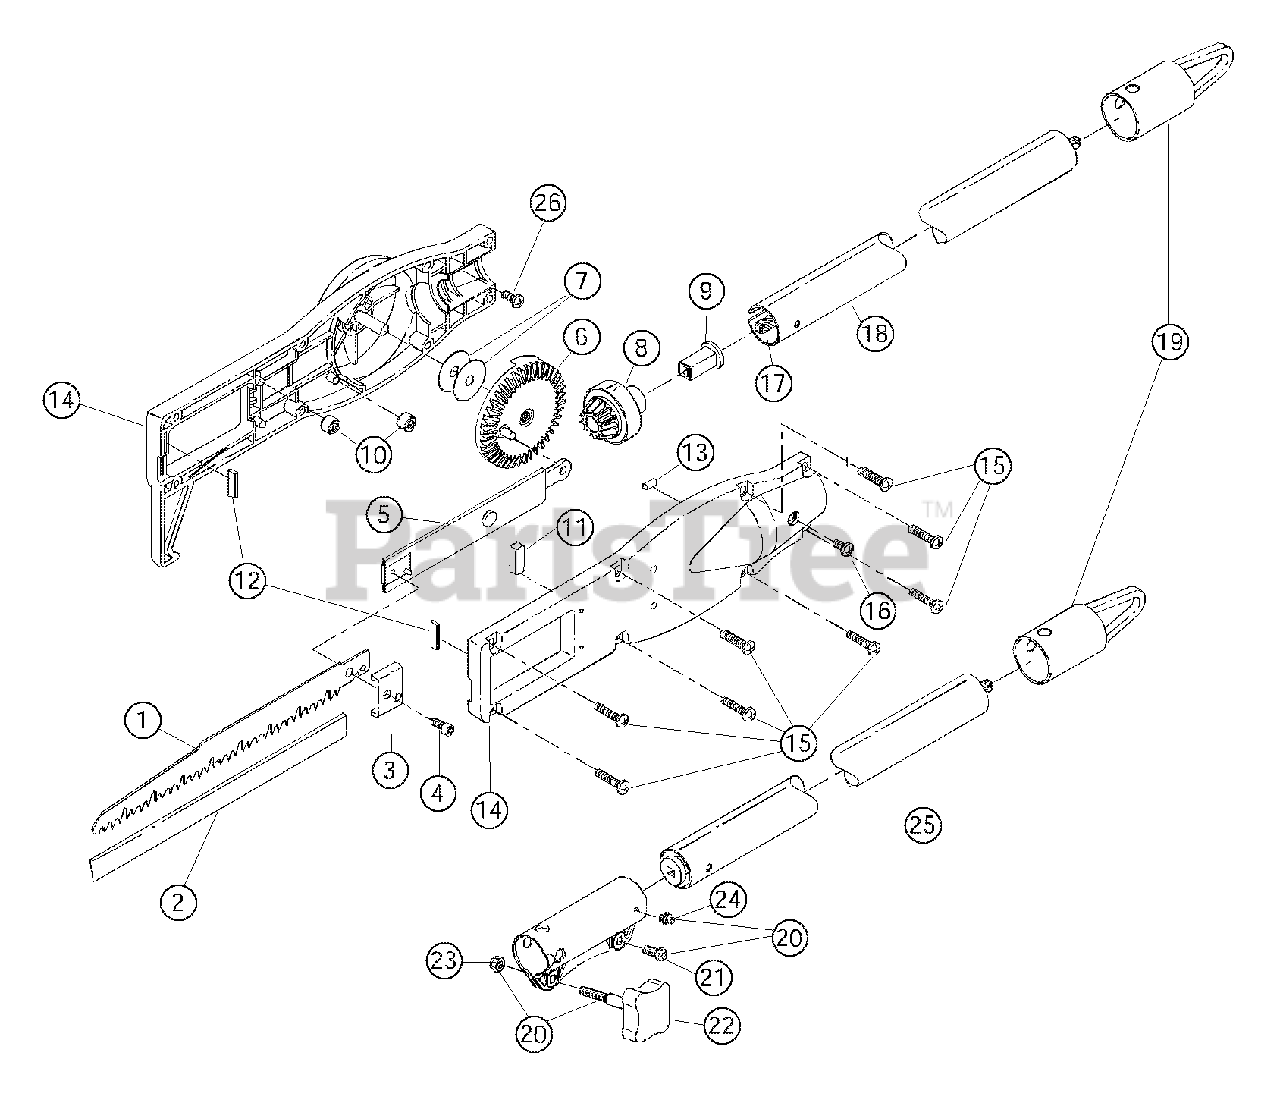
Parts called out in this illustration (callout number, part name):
1	Blade (2 pack)
2	Blade Cover
3	Blade Clamp
4	Blade Clamp Screw & Washer Assembly
5	Arbor Assembly
6	Bevel Gear
8	Pinion Bevel Gear
9	Insulator
10	Slide Bushing
11	Felt Seal
12	Slider (2-pack)
13	Rubber Plug
14	Housing set
15	Housing Screw
16	Anti-Rotation Screw
17	Drive Shaft Assembly
18	Drive Shaft Housing Assembly
19	Hanger
20	Coupler
22	Adjustment Knob
23	Knob Retaining Nut
25	Extension Boom & Flex Shaft Assembly
26	Anti-Rotation Screw
